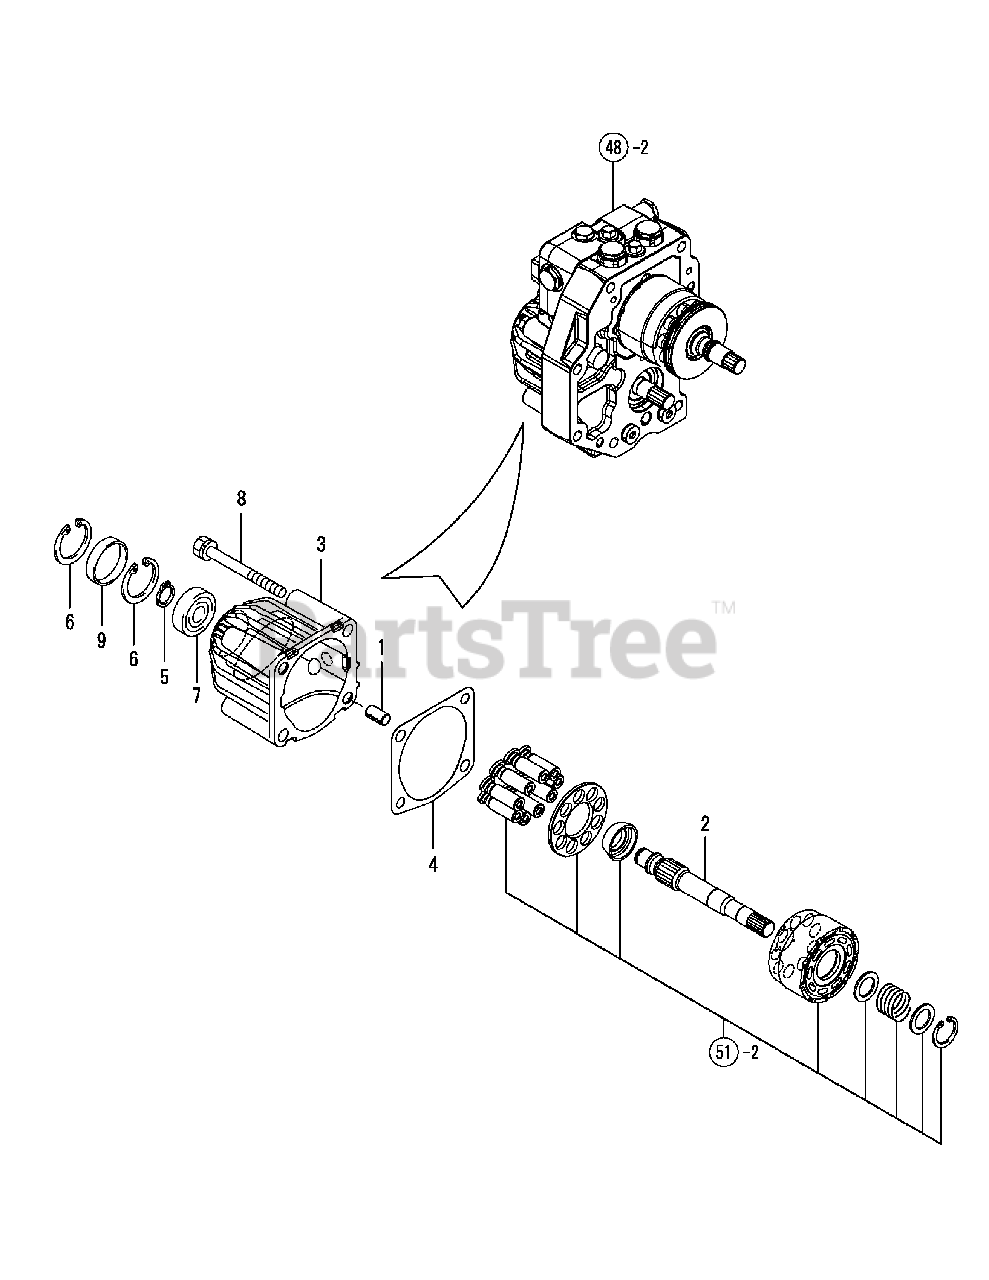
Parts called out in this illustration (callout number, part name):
1	Pin 12X22,Knock
2	Shaft, Motor
3	Case, Motor
4	Packing, Motor Case
7	Ball Bearing
8	Bolt, 10 X 100
